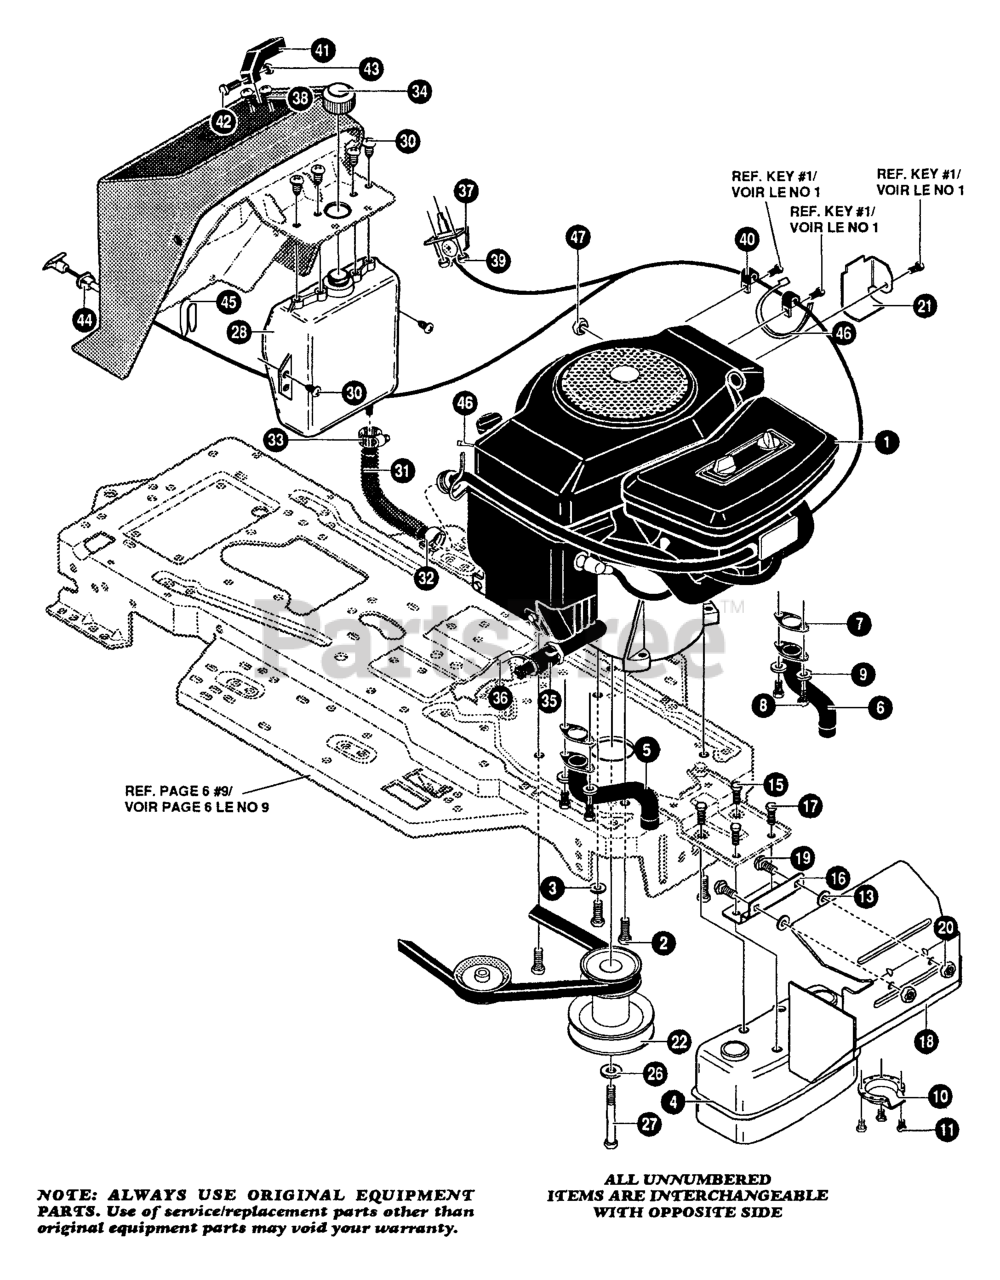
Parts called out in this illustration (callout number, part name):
1	ENGINE *
2	SCREW
4	MUFFLER
5	EX. TUBE, RH
6	EX. TUBE, LH
7	GASKET, MUFFLER
9	WASHER
10	DEFLECTOR
11	SCREW
13	PUSHNUT
16	BRKT, TRANSAXLE
18	HEAT SHIELD
19	SCREW
21	DEFLECTOR
22	PULLEY, ENGINE
26	WASHER
28	TANK, FUEL
31	TUBING, GAS LINE
32	CLAMP, HOSE
33	CLAMP, HOSE
34	CAP, GAS
35	OIL DRAIN ASSY
36	CAP, OIL DRAIN
37	THROTTLE, CONTROL
40	RETAINER
41	KNOB, THROTTLE
44	CHOKE, CONTROL
46	TIE, CABLE
